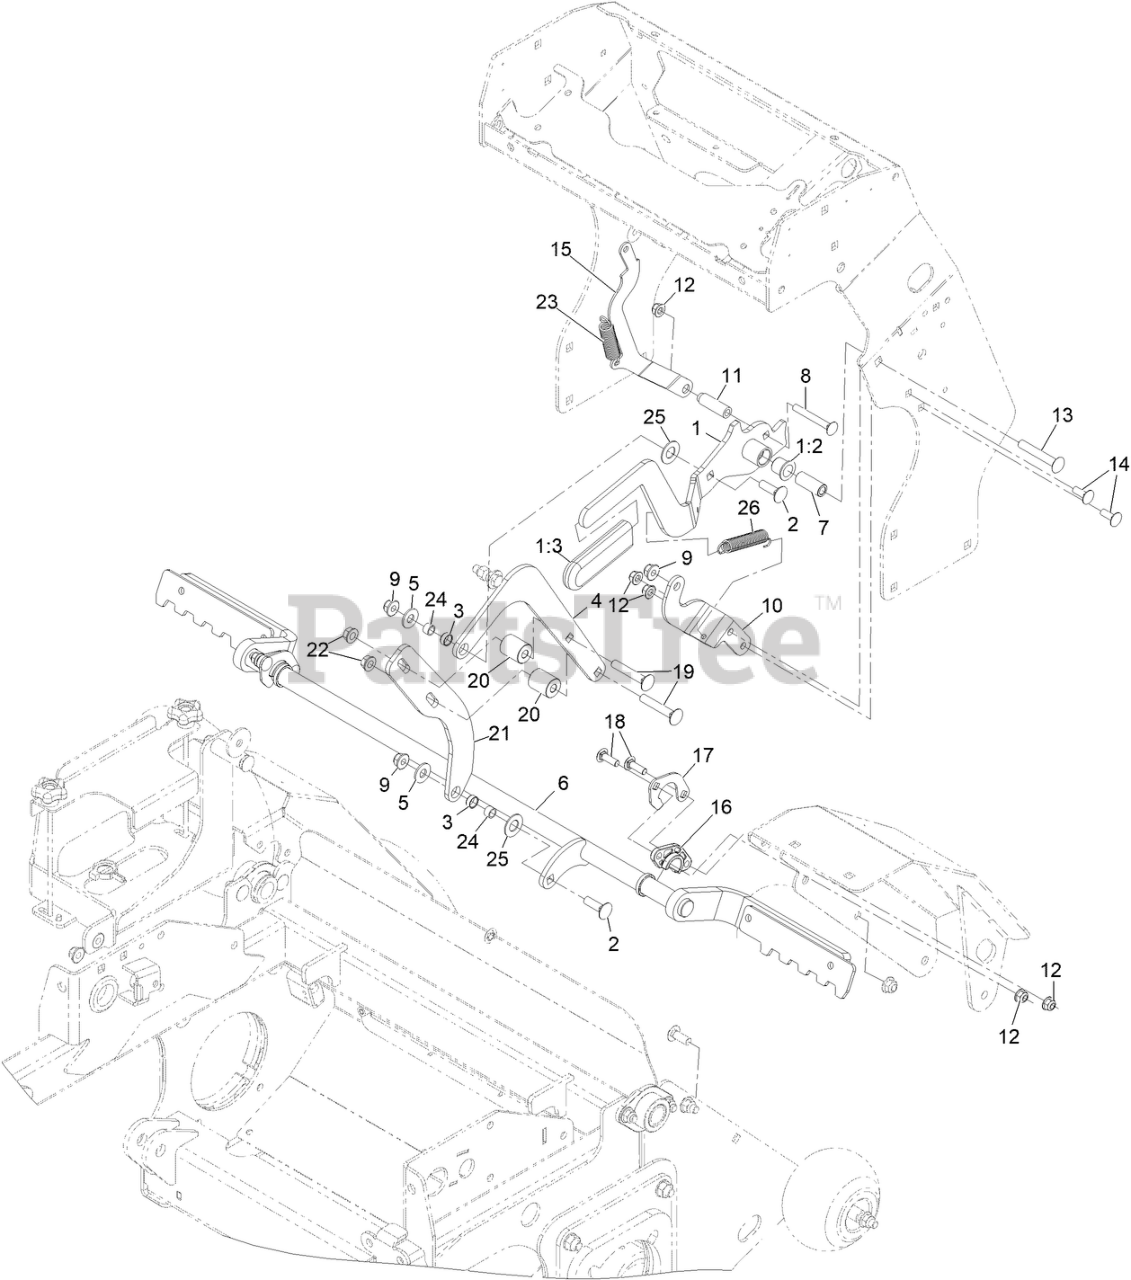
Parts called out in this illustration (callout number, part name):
1	ASM-Handle Brake W/Grip
1:2	BUSHING-FLANGE
1:3	GRIP-LEVER
2	BOLT-CARR
3	BEARING-SLEEVE
4	LINK-BRAKE UPPER
5	WASHER-FLAT
6	ASM-BRAKE SHAFT
7	SPACER-PIVOT
8	SCREW-CARR
9	NUT-HF, NI
10	BRACKET-BRAKE LEVER SUPT
11	SPACER-.31 X 1.25 YZ
12	NUT-HF, NI
13	SCREW-CARR
14	BOLT-CARR
15	Link-Brake Control Lock
16	BEARING-FLANGE
17	SUPPORT, BEARING
18	SCREW-CARR
19	Bolt-Carriage 3/8-16 X 2 1/4
20	SPACER-.39 IDX1.0 ODX1.2 L
21	LINK - LOWER BRAKE
22	NUT-HHF, WHIZ
23	SPRING-EXTENSION
24	SPACER-BRAKE PIVOT
25	WASHER-PLASTIC
26	SPRING-EXTENSION
